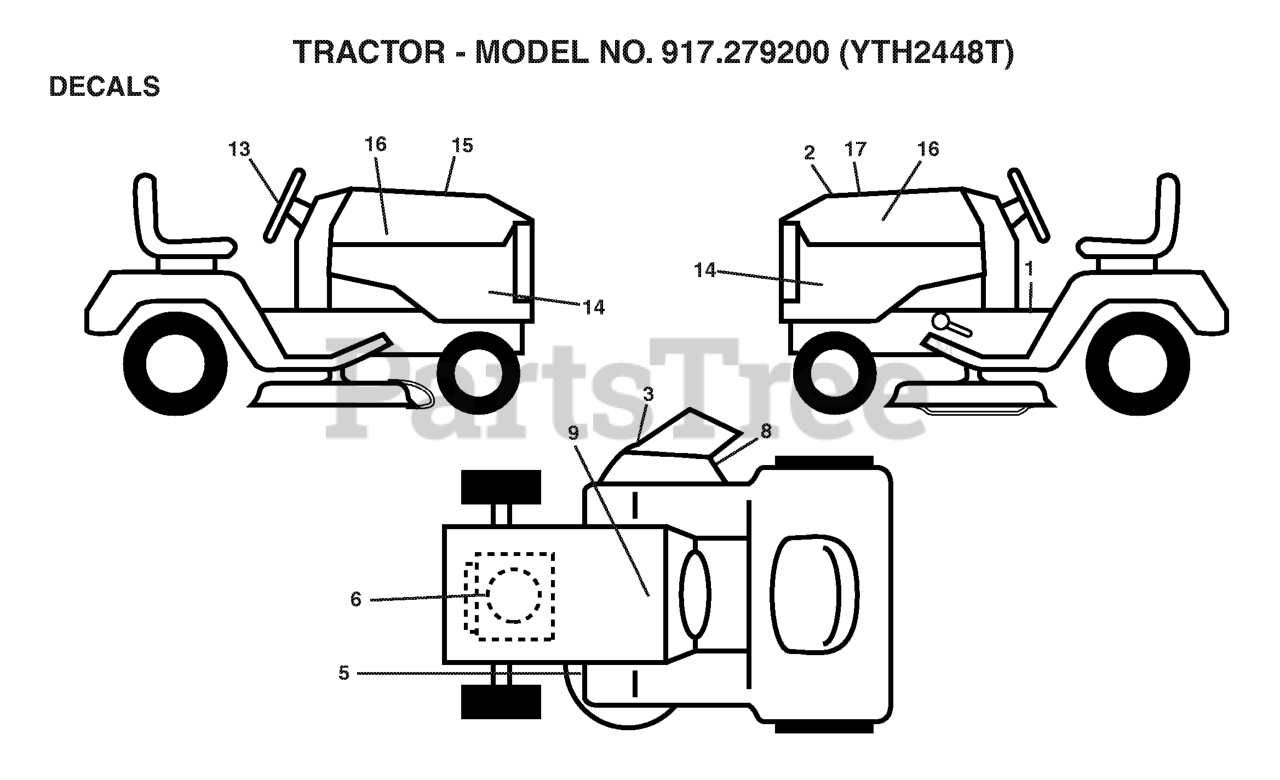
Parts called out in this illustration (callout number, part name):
1	DECAL.FENDER.OPER.TEX.
2	DECAL.HOOD.TOP.INSERT.
3	DECAL.WARN.KEEP.HAND.AWAY
5	DECAL CLUTCH/BRAKE
6	DECAL.ENG.B&S.24
8	DECAL.MOWER.SCH.48/54
9	DECAL BTRY SYMBOLS
13	DECAL.WHEEL.STRG.LGN.H
14	DECAL.PANEL.SIDE.YTH24
15	DECAL HOOD CUST. RESP.
16	DECAL.HOOD.NAMELOGO.HUSQ
17	DECAL.RPL.B&S.24HP.48"
